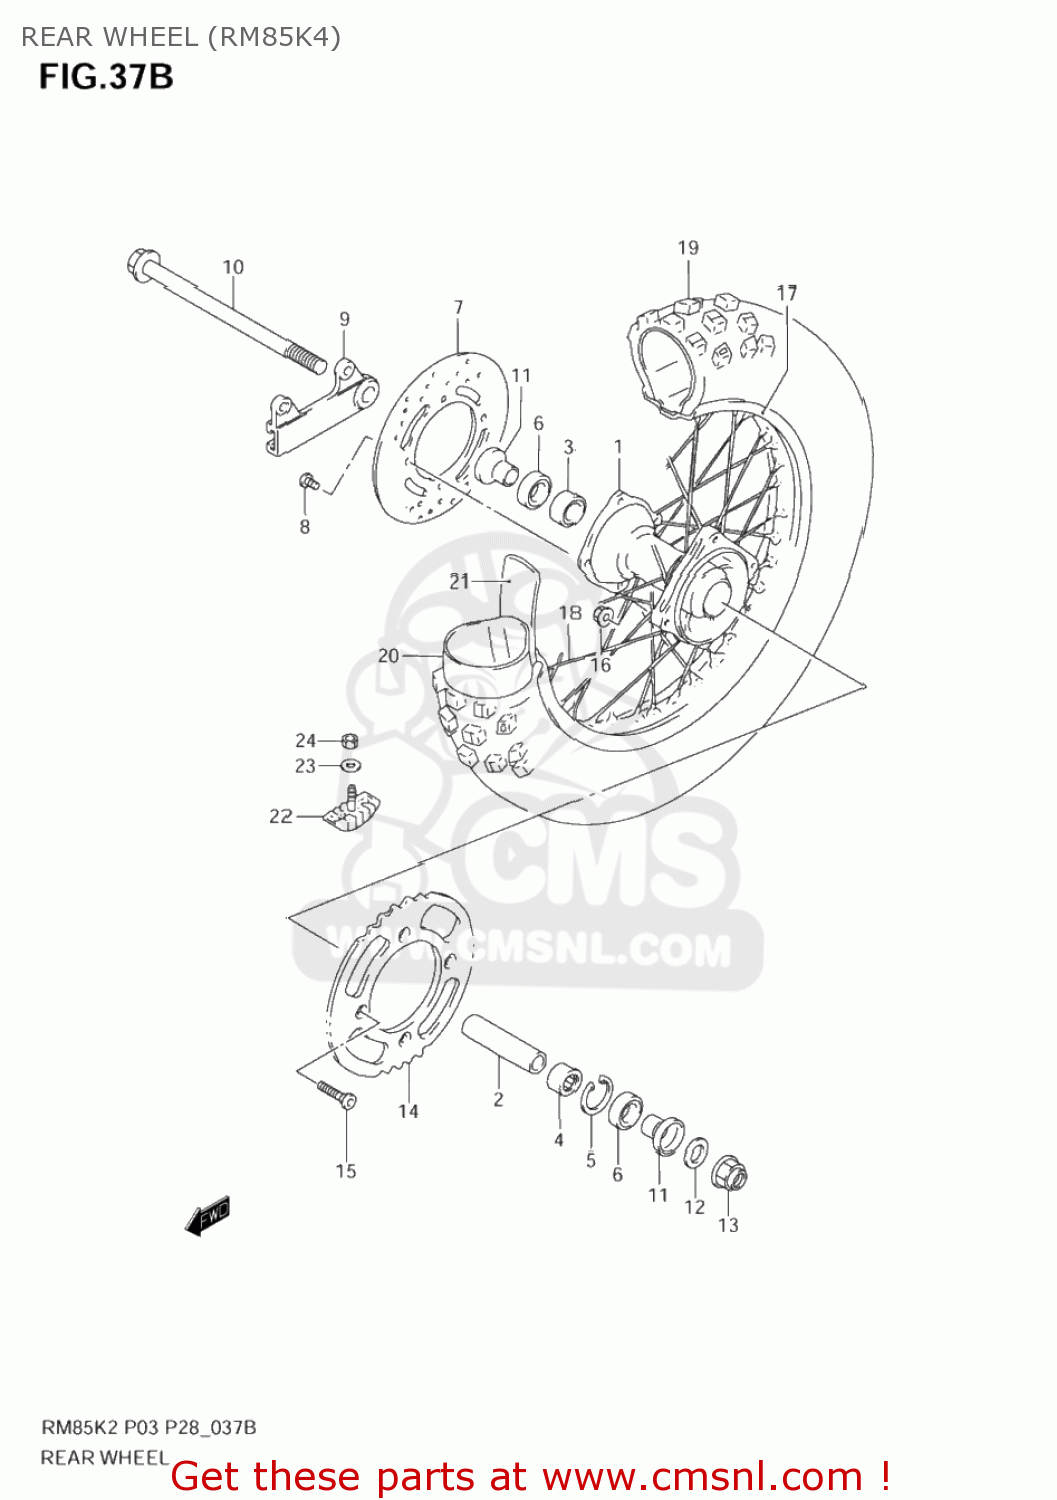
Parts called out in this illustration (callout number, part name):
1	HUB,RR WHEEL
2	SPACER,RR HUB BEARING
3	BEARING
4	BEARING(15X35X11)
5	CIRCLIP
6	SEAL,OIL(20X35X7)
7	DISC,REAR BRAKE
8	SCREW
9	BRACKET,RR CALIPER
10	AXLE,RR
11	SPACER,RR AXLE
12	WASHER
13	NUT
14	SPROCKET,RR(47T)
15	BOLT(8X30.5)
16	NUT
17	RIM,RR WHEEL(1.60X14 AL)
18	SPOKE SET,RR WHEEL
19	TIRE,RR(90/100 14)
20	TUBE ASSY,WHEEL INNER
21	PROTECTOR,WHL INR TUBE
22	STOPPER,BEAD(1.85)
23	WASHER
24	NUT
